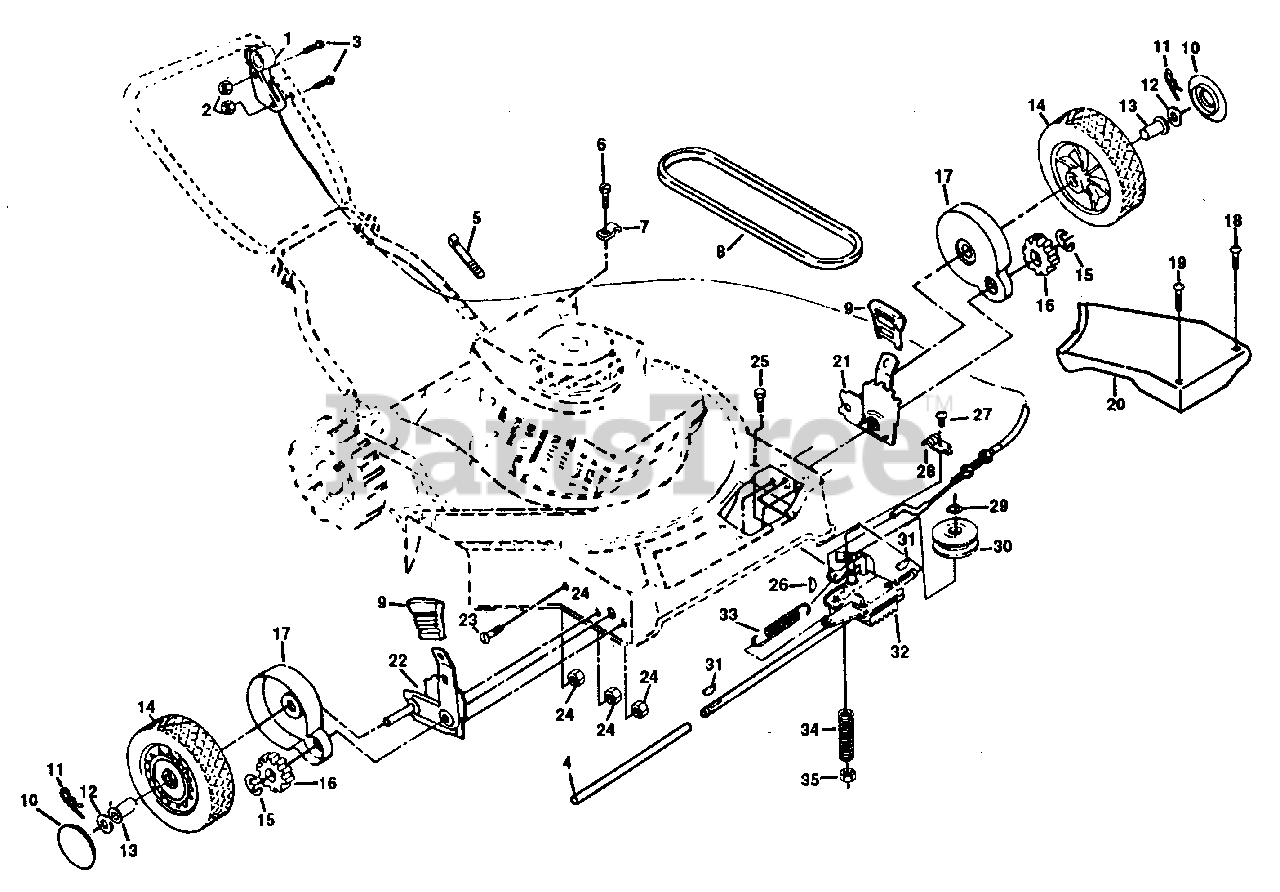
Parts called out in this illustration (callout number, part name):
1	Drive Control Cable (AYP part number)
2	Locknut (AYP part number)
3	Machine Screw #10-24 x 2 (AYP part number)
4	Drive Shaft Cover (AYP part number)
5	Wire Tie (AYP part number)
6	Hex Washer Head Screw #10-24 x 1/2 (AYP part number)
7	Cable Guide Clip (Housing) (AYP part number)
9	Selector Knob (AYP part number)
11	Retainer Clip (AYP part number)
12	Washer (AYP part number)
13	Wheel Bushing (AYP part number)
14	Wheel & Tire Assembly (Front) 8.00 x 1.75 (AYP part number)
15	External E-Ring (AYP part number)
16	Pinion (AYP part number)
17	Dust Cover (AYP part number)
18	Pan Head Machine Screw #10-24 x 1-3/4 (AYP part number)
19	Pan Head Machine Screw #10-24 x 2-3/4 (AYP part number)
20	Drive Cover (AYP part number)
21	Wheel Adjusting Assembly (Left) (AYP part number)
22	Wheel Adjusting Assembly (Right) (AYP part number)
23	Flat Head Machine Screw 1/4-20 x 3/4 (AYP part number)
24	Locknut 1/4-20 (AYP part number)
25	Hex Head Bolt 1/4-20 x 2-3/4 (AYP part number)
26	Woodruff Key #213 (AYP part number)
27	Screw #10-24 (AYP part number)
28	Cable Clamp (Adj. Bracket) (AYP part number)
29	Retaining Ring (AYP part number)
30	Drive Pulley (AYP part number)
31	Woodruff Key #3 (AYP part number)
32	Gear Case Assembly (AYP part number)
33	Spring (AYP part number)
35	Locknut 1/4-20 (AYP part number)
